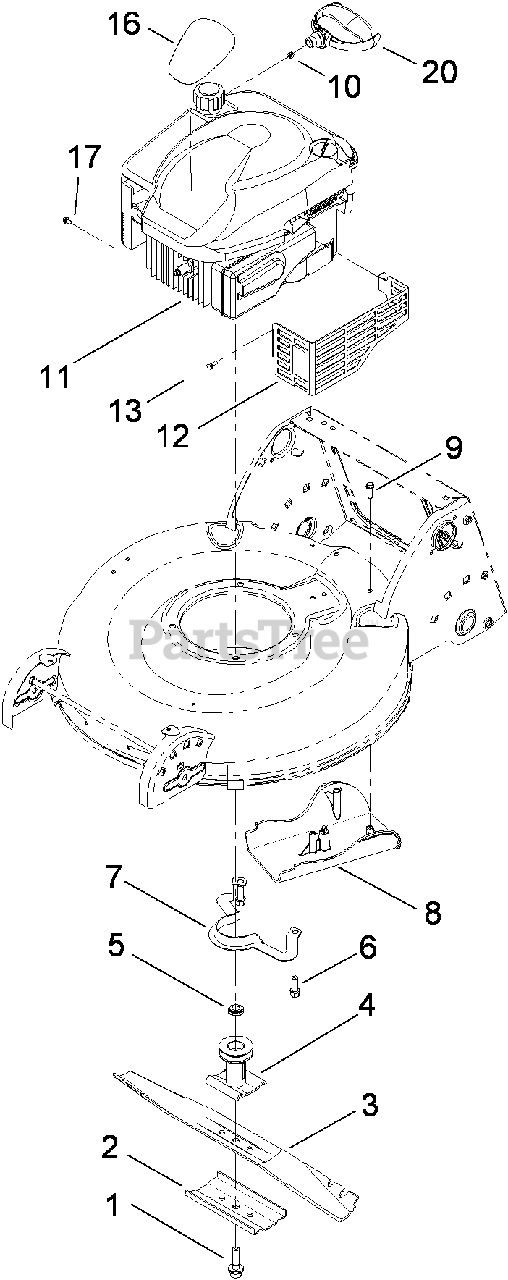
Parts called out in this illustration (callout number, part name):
1	BOLT-BLADE
2	SUPPORT-BLADE
3	BLADE-21 INCH
4	BLADE DRIVER ASM
5	Spacer-Driver
6	SCREW-HWH
8	COVER-BELT
9	SCREW-HWH
10	STOP-ROPE
12	SHIELD-MUFFLER
13	SCREW-TAPTITE
16	DECAL-ENGINE
17	SCREW-HWH
20	HANDLE-RECOIL
